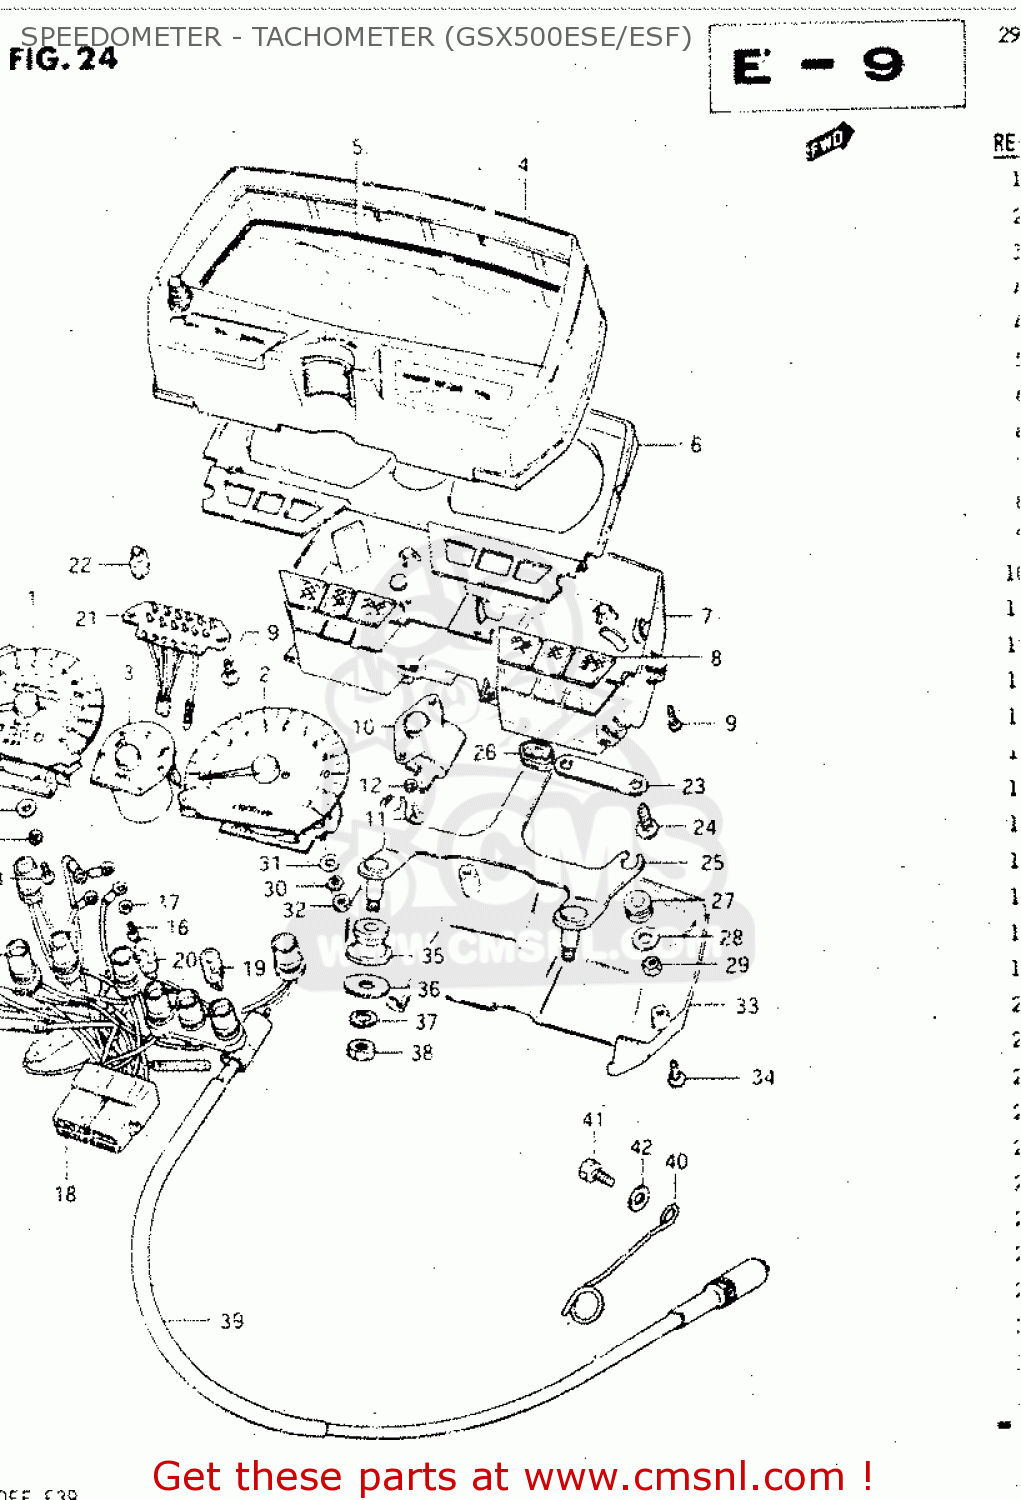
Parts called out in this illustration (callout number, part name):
1	SPEEDOMETER (KILO)
2	TACHOMETER
3	METER,FUEL
4	HOOD,METER
5	GLASS,SPEEDOMETER
6	PLATE, WINDOW
7	CASE,METER,INNER
8	LENS SET,PILOT
9	SCREW,GEAR INDICATOR
10	BOX,GEAR
11	SCREW 4X10
12	LOCK WASHER
13	SCREW
14	LOCK WASHER
15	WASHER
16	SCREW
17	WASHER
18	SOCKER
19	BULB(12V10W,TOKAI DENSO)
20	BULB(12V1.7W,T10,WB121)
21	SOCKET,GEAR INDICATOR
22	BULB(14V1.12W)
23	PLATE,COUPLER
24	SCREW
25	BRACKET,METER
26	CUSHION,METER
27	CUSHION,METER
28	WASHER,METER
29	NUT
30	LOCK WASHER
31	WASHER,SPEEDOMETER
32	NUT
33	COVER,METER,UNDER
34	SCREW
35	CUSHION,METER BRACKET
36	WASHER (8.5X20X1.6)
37	LOCK WASHER
38	NUT
39	CABLE ASSEMBLY,SPEEDOMETER
40	CLAMP,SPEEDOMETER CABLE
41	BOLT, UPPER
42	WASHER
